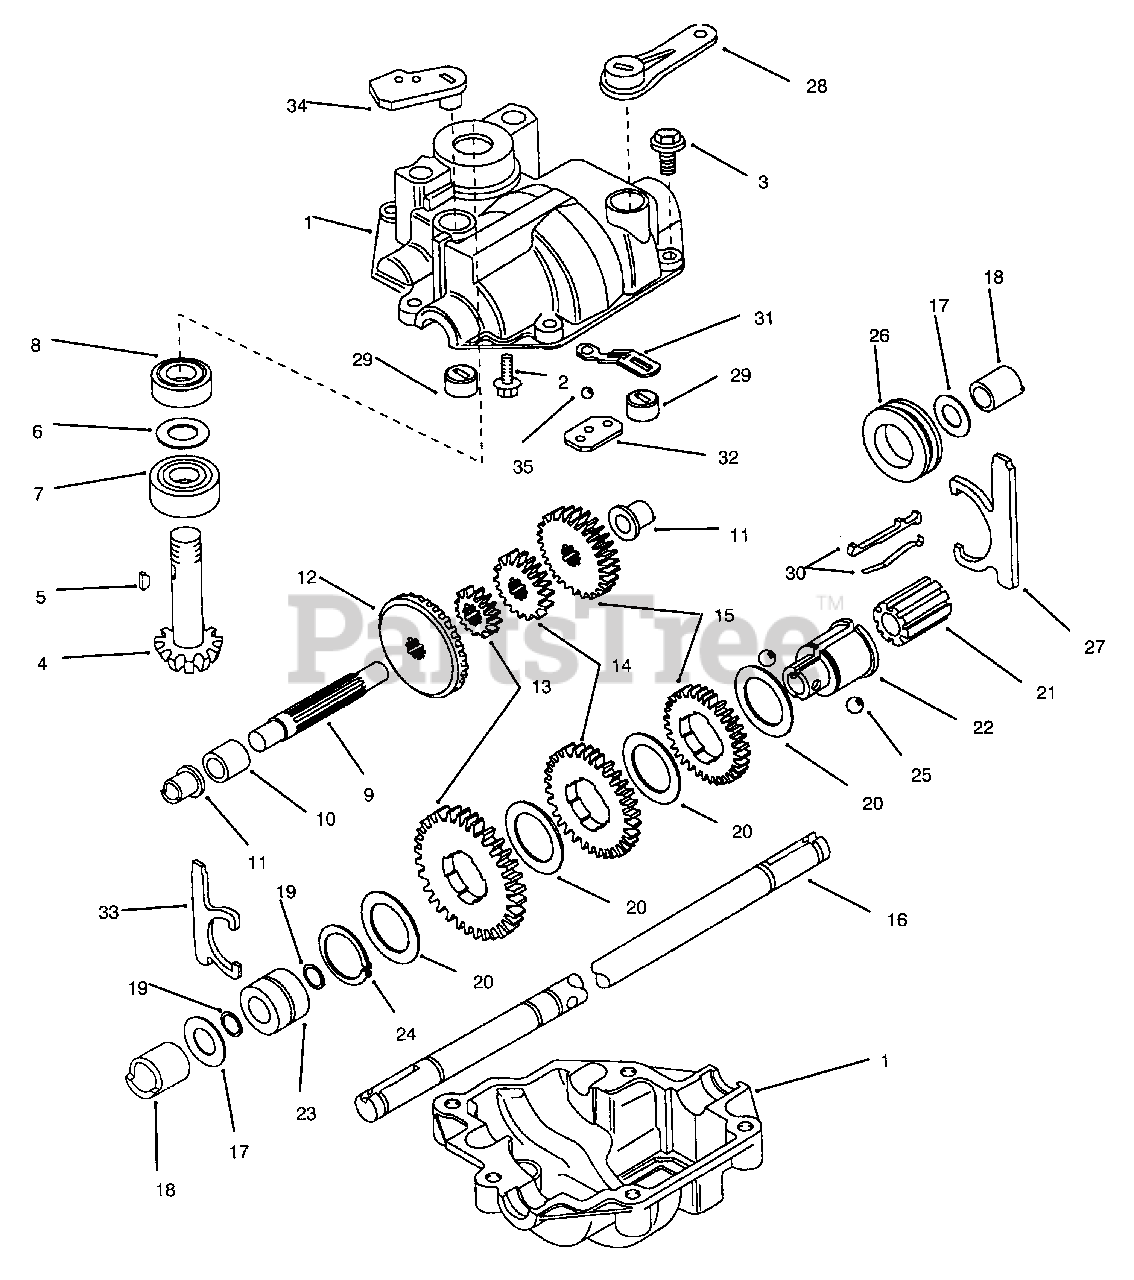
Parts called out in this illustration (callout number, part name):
1	Kit-Upper & Lower Case (Incl. Sealant)
2	Screw-Tapping
3	Screw-Tapping
4	Shaft-Input
5	Key-Woodruff
7	Bearing-Lower
8	Bearing-Upper
9	Kit-Shaft, Reduction (Incl. Ref. No. 10-11)
11	Bushing Set
12	Ring Gear
13	Gear Set
14	Gear Set
15	Gear Set
16	Kit-Axle Shaft (Incl. Ref. No. 17-19)
18	Bushing Set
19	Ring-Snap
21	Key-Holder,
22	Collar-Shift
24	Ring-Snap
25	Ball
26	Collar-Sliding
27	Fork-Shift
28	Arm-Shift
29	Support-Fork
30	Spring & Key-Shift
33	Fork-Clutch
34	Arm-Clutch
